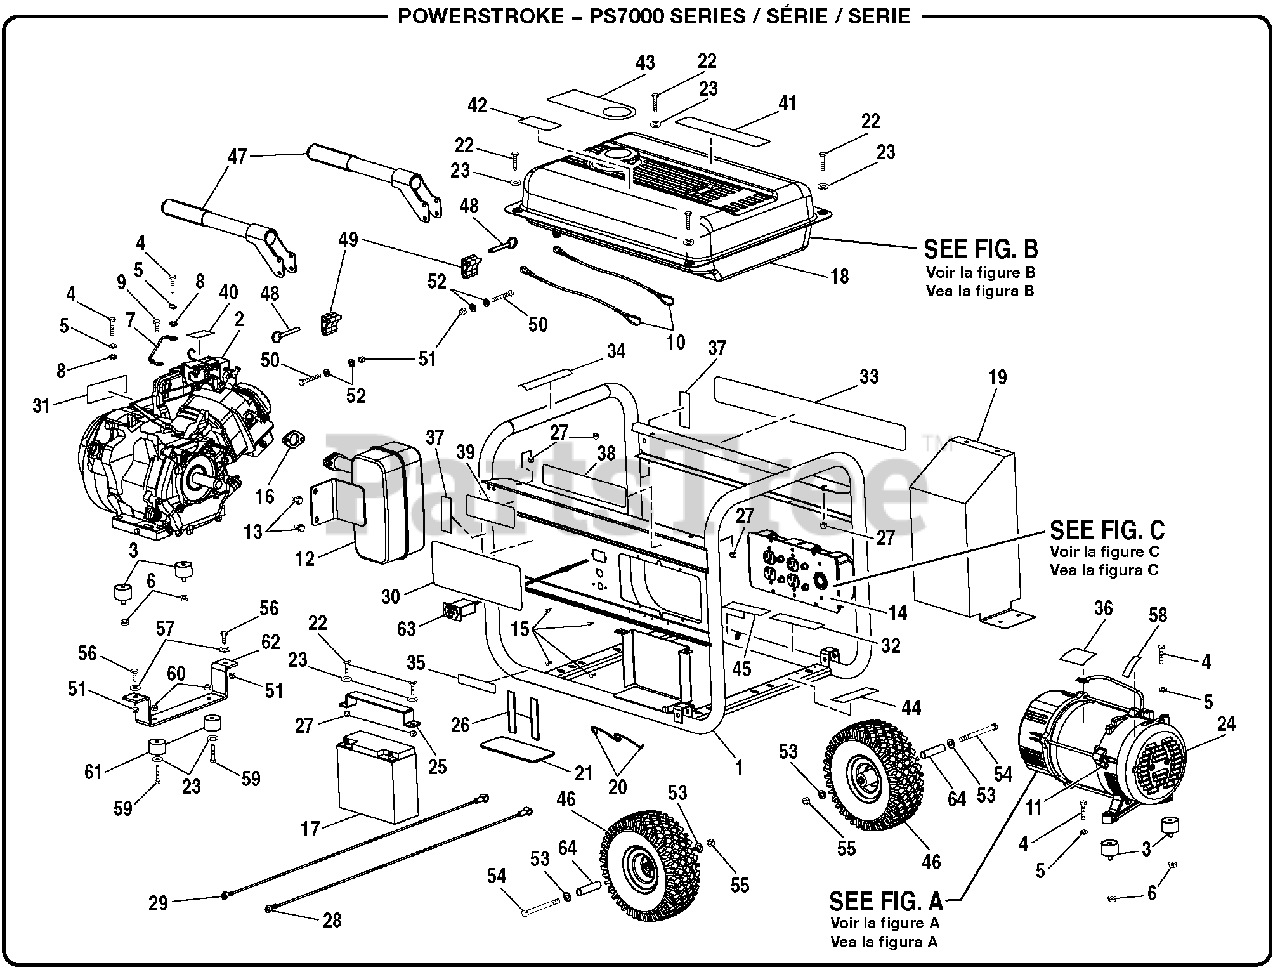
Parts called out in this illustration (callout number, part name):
1	Carrier Assembly
4	Bolt (5/16-18 x 1-1/2 in., Hex Hd.)
5	Lock Washer (5/16 in.)
6	Flange Nut (5/16-18, Hex Hd.)
7	Ground Wire Assembly
8	Star Washer (5/16 in.)
9	Bolt (5/16-18 x 3/4 in., Hex Hd.)
10	Lanyard (3/16 in.)
11	Ground Lug
13	Bolt (5/16-24 x 5/8 in.)
14	Control Panel Assembly
15	Screw (6-20 x 3/8 in.)
16	Muffler Gasket (supplied by Honda)
17	Battery
18	Fuel Tank Assembly
19	Heat Shield
20	Cord Retainer
21	Battery Box Gasket
22	Bolt (1/4-20 x 1 in., Hex Hd.)
23	Washer (1/4 in.)
24	Generator Head w/AVR
25	Battery Hold Down Bracket Assembly
26	Gasket (Battery Hold Down Bracket)
27	Lock Nut (1/4-20)
28	Battery Cable (Red)
29	Battery Cable (Black)
30	Logo Label
31	Starting Instructions Label
32	Hot Surface Label
33	Danger Label
34	Fire Danger Label
35	Engine Lubricant Label
36	Data Plate Label
37	Locking Pin Label
38	Honda Label
39	Electric Start Label
40	Choke Label
41	Quick Start Label
42	CPSC Label
43	Hangtag (Engine Warning)
44	Ground Warning Label
45	Combustion Warning Label
46	Wheel Assembly
47	Handle Assembly
48	Release Pin (5/16 x 2 in.)
49	Handle Bracket Spacer
50	Bolt (5/16-18 x 2-1/4 in., Hex Hd.)
51	Lock Nut (5/16)
52	Washer (5/16 in.)
53	Washer (3/16 in.)
54	Bolt (3/8-16 x 4-1/4 in., Hex Hd.)
55	Nut (3/8-16)
56	Bolt (5/16-18 x 1 in., Hex Hd.)
57	Flat Washer (5/16 in.)
58	Ground Label
59	Bolt (1/4-20 x 1-1/2 in., Hex Hd.)
60	Lock Nut (1/4-20)
61	Rubber Foot
62	Front Foot
63	Hour Meter (120 Volt)
64	Wheel Spacer
